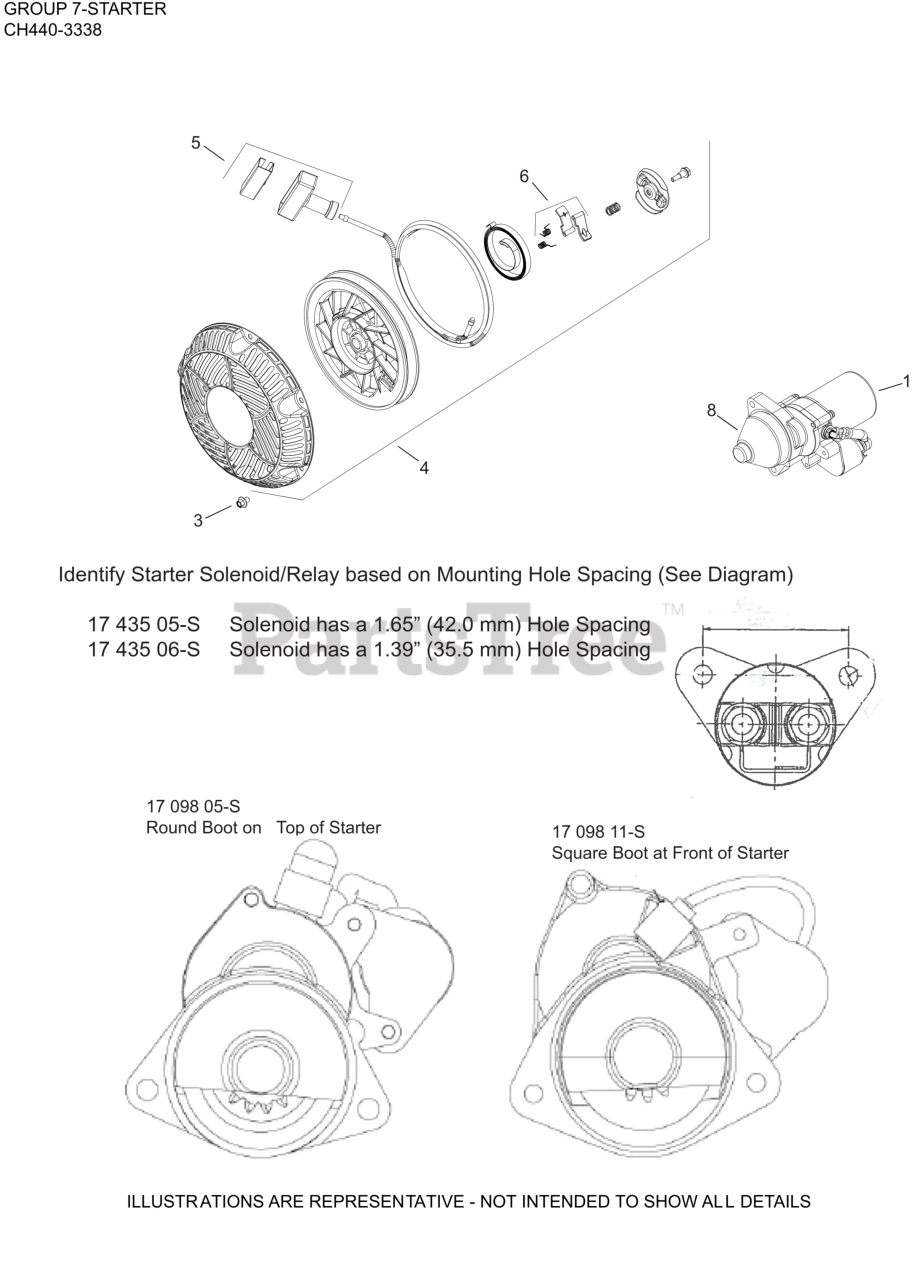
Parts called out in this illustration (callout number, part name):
1	ELCTRC START,BENDIX DRV W/SOLENOID
3	SCREW, M6 X 8 HEX FLANGE HEAD
4	RETRACTABLE STARTER ASSY-(#1716522S)
5	KIT, HANDLE
6	KIT, PAWL REPAIR
8	KIT, STARTER DRIVE
